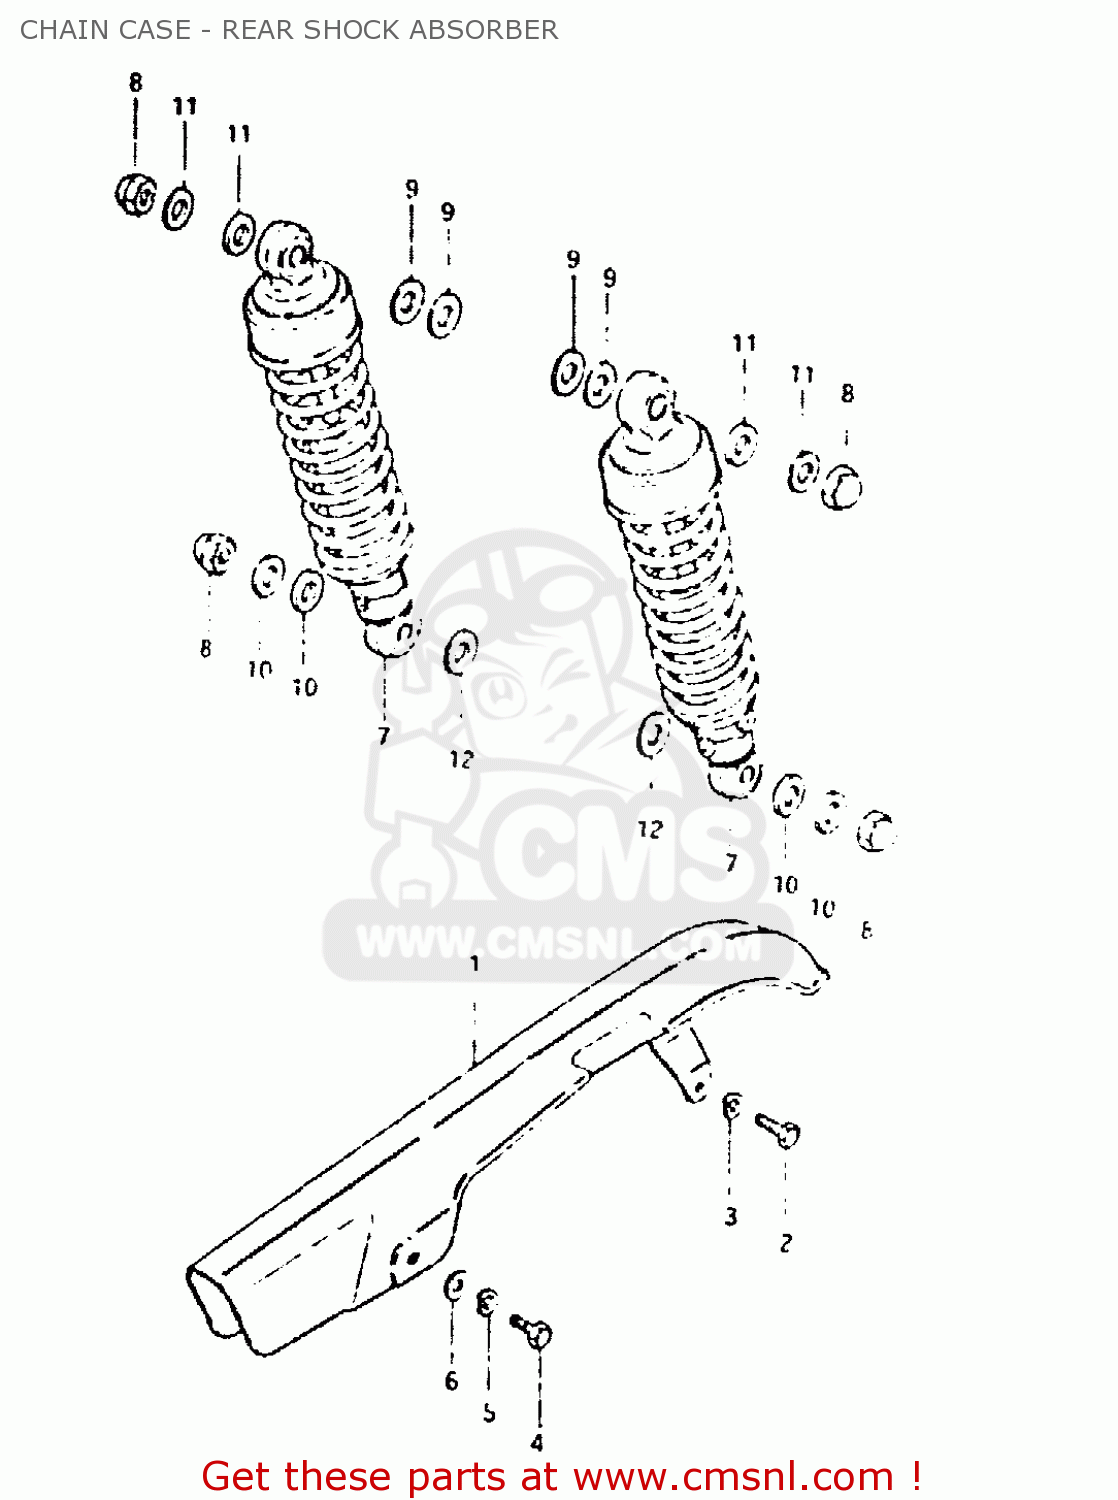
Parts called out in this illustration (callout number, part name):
1	CASE,CHAIN
2	BOLT, UPPER
3	LOCK WASHER
4	BOLT
5	LOCK WASHER
6	WASHER
7	ABSORBER ASSEMBLY,REAR SHOCK
8	NUT, LOWER LH
9	WASHER
10	WASHER
11	WASHER(10.5X24X3.2)
12	WASHER (12.5X24X1.6)
